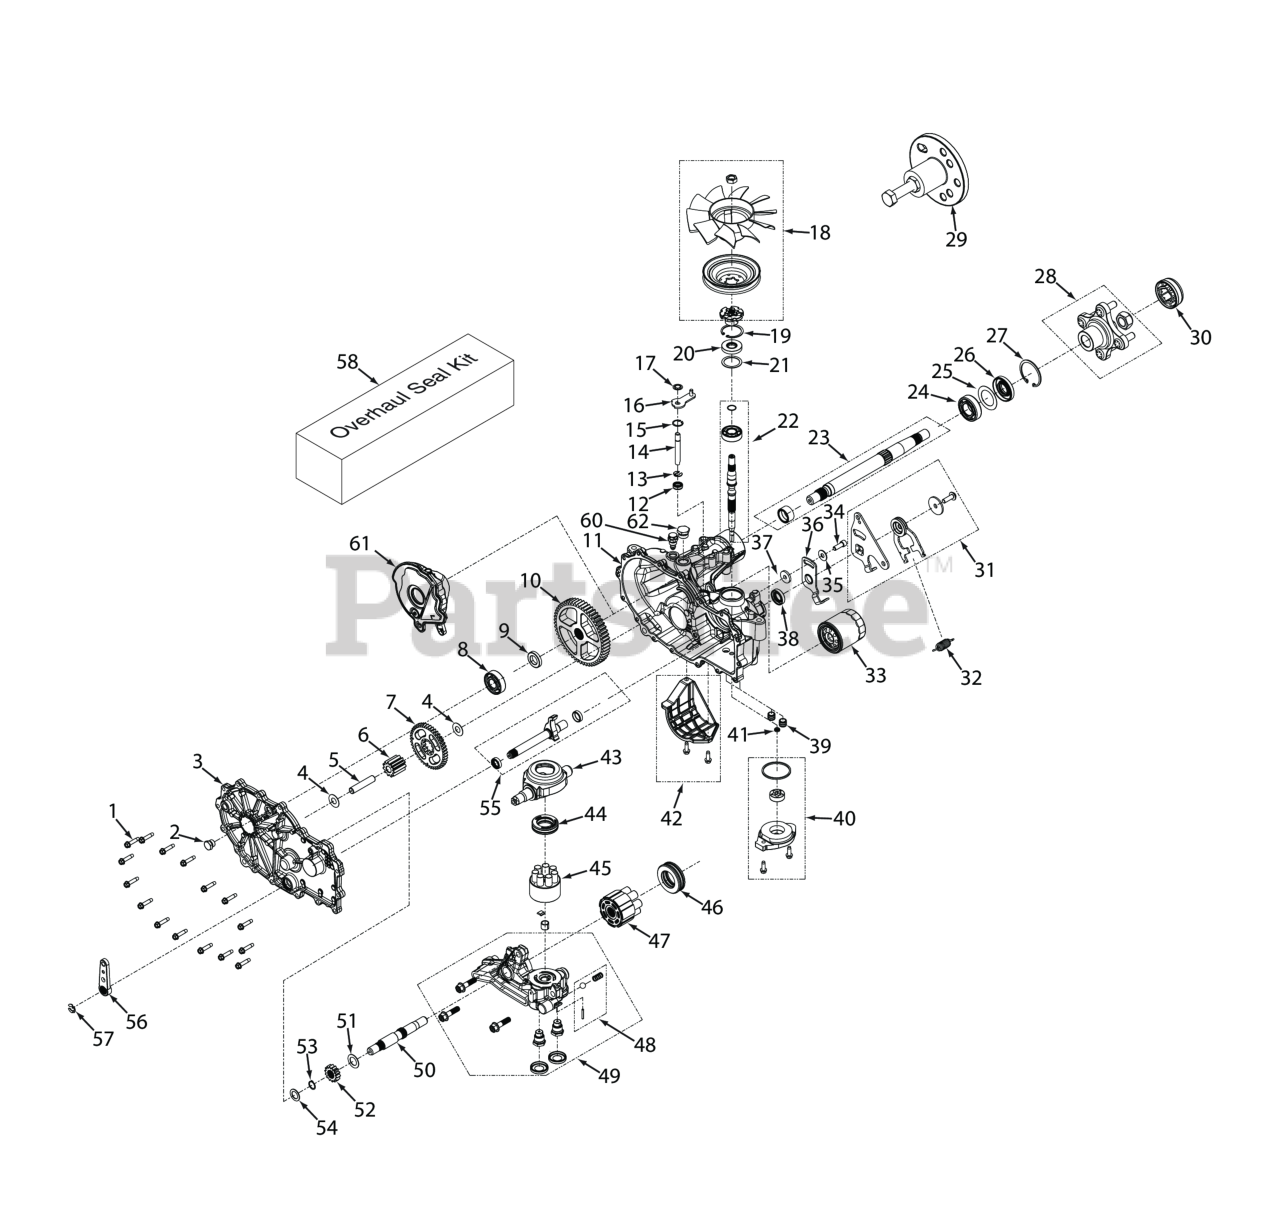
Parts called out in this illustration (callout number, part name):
1	Bolt, Hex Head 1/4-20 x 1-1/8"
2	Plug, External Hex Vent 9/16-18
3	Kit, Side Cover LH
4	Washer, .5 x 1.0 x .03
5	Jackshaft Pin
6	Gear, 11T Steel
7	Gear, 45T
8	Kit, Bearing
9	Spacer, .750 x 1.320 x .257
10	Gear, 54T
11	Kit, Main Housing LH, Charge, Control
12	Seal, Lip, .375 x .75 x .25
13	Ring, .Retaining .375 External
14	Rod, By-Pass
15	R i n g , Retaining .750 Internal
16	Arm, Bypass (LH)
17	Ring, Retainging .375 External
18	Kit, Fan/Pulley
19	R i n g , Retaining 2.06 Internal
20	Seal, Lip 17 x 40 x 7
21	Washer, 1.23 x 1.56 x .04
22	Kit, Input Shaft
23	Kit, Shaft, Axle
24	Bearing, Ball 1.0 x 52 x 15 Open
25	Spacer, 1.355 x 2.035 x .021
26	Seal, Lip TC4 1.0 x 2.06 x .38
27	R i n g , Retaining 2.06 Internal
28	Hub, 4-Bolt
29	Kit, Hub Puller
30	Cap, Axle
31	Kit, RTN Bi-Directional (Right Side)
32	Spring, Extension, RTN - 44lbs
33	Filter, Oil
34	Bolt, Hex Head Cap Screw 5/16-24 x 1" Patch
35	Washer, 7/16 x 7/8 OD x .06 HT
36	Arm, Neutral (Left Side)
37	Spacer, .32 ID x 1.005 OD x .1495 Thk
38	Seal, Lip 18 x 32 x 7
39	Tube, Charge Triple O-ring
40	Kit, Charge Pump
41	Kit, Gerotor Seal
42	Kit, Filter Guard (LH)
43	Trunnion, Swashplate
44	Ball Thrust Bearing
45	Kit, Cylinder Block
46	Thrust Ball Bearing Assembly
47	Kit, 16cc Cylinder Block Assembly (steam
48	Kit, Charge Relief
49	Kit, Center Section, LH Charge
50	Shaft, Motor
51	Washer, .72 x 1.16 x .04
52	Gear, 14T Steel
53	Ring, Retaining .625
54	Washer, HT .62 ID x 1.0 OD x .05 Thick
55	Kit, Inboard, RH Rot B / LH Rot A (LH)
56	Handle, Brake
57	Ring, Retaining External .375"
58	Kit, Seal (ZT-2800)
60	Fitting 9 /16 - 18, Breather
61	Expansion Tank, Internal LH
62	Plug, 3/4-16
